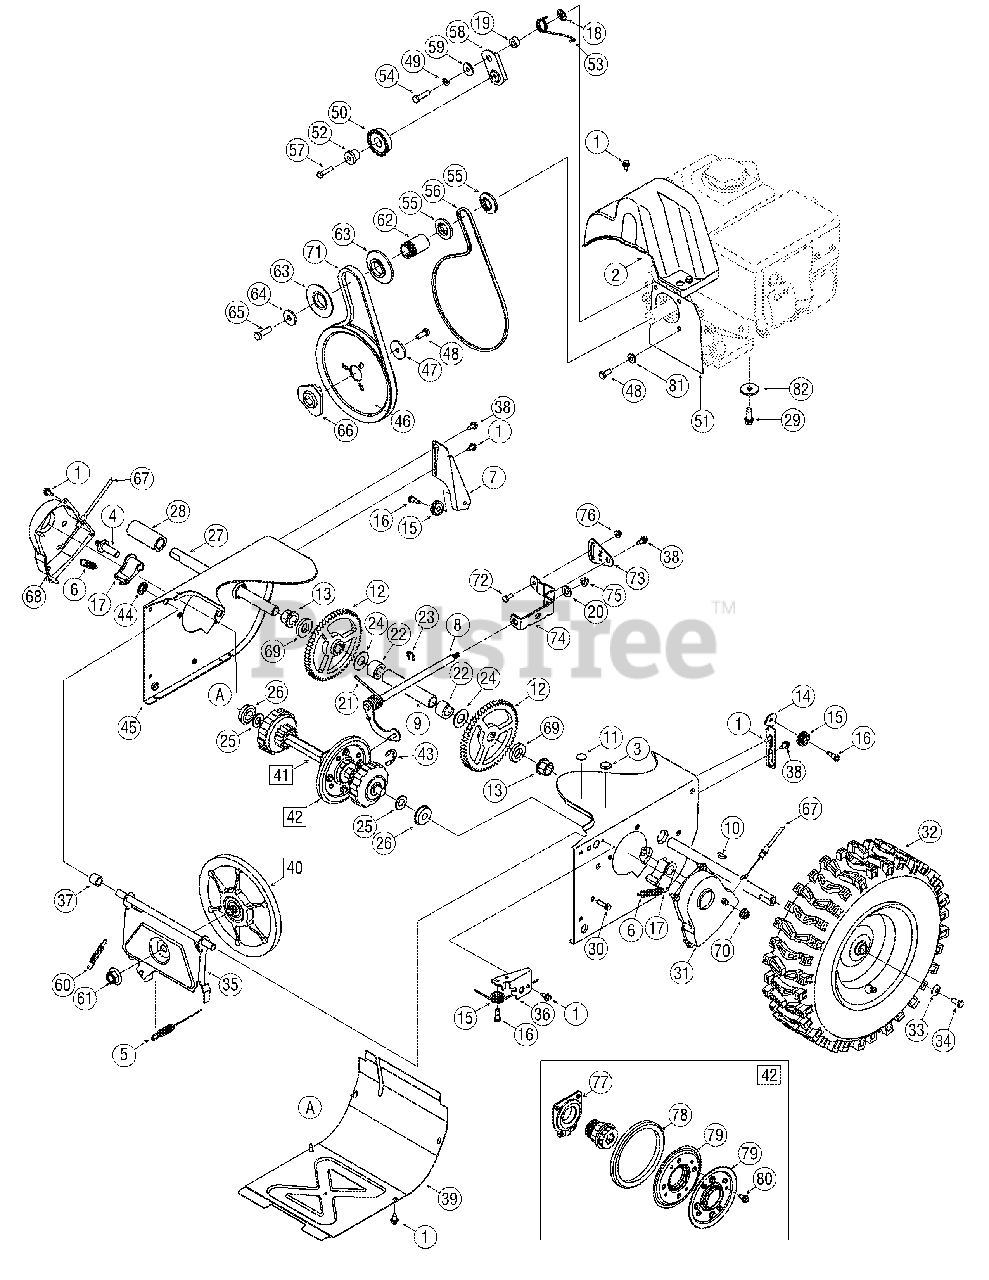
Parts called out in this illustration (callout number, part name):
1	AB Screw, 1/4-20 x 0.625
2	Belt Cover
3	Plug, 3/8 ID
4	Actuator Shaft
5	Drive Clutch Cable
6	Extension Spring
7	Drive Clutch Cable Guide Bracket
8	Shift Rod Assembly
9	Axle Support Tube
10	Hi Pro Key
11	Plug, 1/2 ID
12	Gear, 56T
13	Hex Flange Bearing
14	Auger Clutch Cable Guide Bracket
15	Cable Roller
16	C Screw, 1/4-28 x 0.375
17	Dogg Assembly - LH
17	Dogg Assembly - RH
18	Push-on Nut
20	Washer, Flat
21	Torsion Spring, .750ID x .968 Lg.
22	Spacer
23	E Ring
24	Flat Washer, .76 x 1.49 x .06
25	Flat Washer
26	Ball Bearing
28	Spacer
29	TT Sems Screw, 3/8-16 x 1.0
30	TT Screw, 1/4-20 x 1.0
31	Shaft Retainer - LH
32	Wheel Complete - LH
32	Wheel Complete - RH
33	Bell Washer
34	Hex Bolt, 5/16-24 x 0.75
35	Friction Wheel Support Brkt. Assy.
36	Auger Cable Guide Bracket
37	Spacer
38	Shoulder Screw
39	Frame Cover
40	Friction Wheel Disc Assembly
41	Drive Shaft Assembly
42	Friction Wheel Assembly
43	Retainer Ring
44	Speed Nut
45	Wheel Drive Frame
46	Auger Pulley
47	Flat Washer
48	Hex Bolt, 5/16-24 x 0.875
49	Lock Washer
50	Idler Pulley Assembly
51	Plt., Cvr.
52	Spacer
53	Torsion Spring
54	Hex Screw, 5/16-24 x 1.25
55	Pulley Half
56	Belt, Wheel Drive
57	TT Screw, 1/4-20 x 1.25
58	Drive Clutch Idler Bracket
59	Shoulder Spacer
60	Extension Spring
61	Flange Nut, 5/8-18
62	Spacer
63	Pulley Half
64	Flat Washer
65	Hex Bolt, 3/8-24 x 1.25
66	Pulley Adapter
67	Steering Cable
68	Shaft Retainer - RH
69	Axle Spacer
70	Flange Lock Nut, 3/8-16
71	V-Belt,.500 x 37.00 Lg
72	Hex Screw, 1/4-20 x .620
73	Speed Selector Pivot Bracket
74	Speed Selector Shift Bracket
75	Flange Lock Nut, 5/16-18
76	Flange Lock Nut, 1/4-20
77	Friction Wheel Bearing Assembly
78	Friction Wheel
79	Friction Plate
80	Screw, 1/4-14 x .625
81	Shoulder Spacer
82	Washer, Flat, .38 x 1.38 x .125
